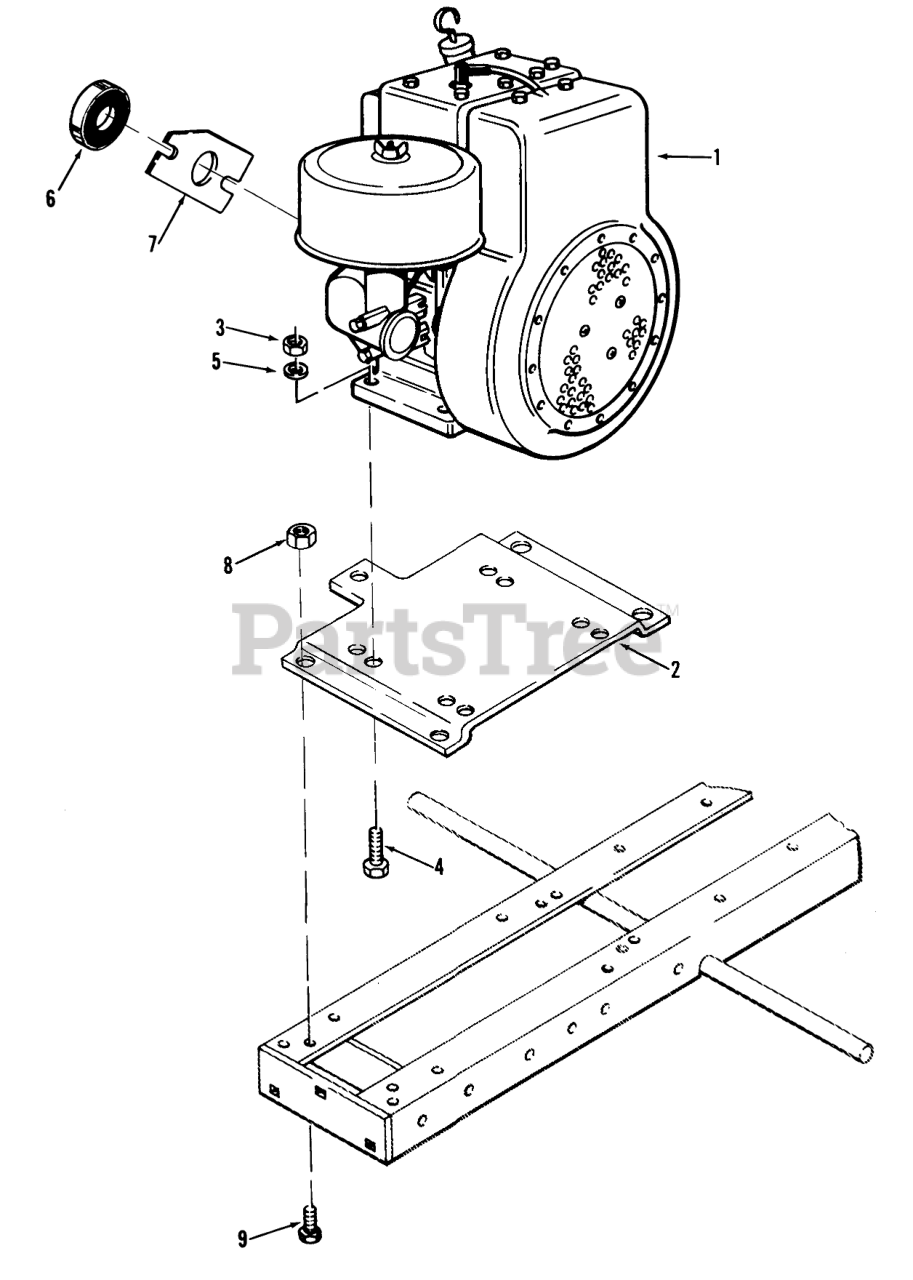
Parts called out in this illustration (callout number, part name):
1	Engine-11 HP Briggs & Stratton 252417 Type 0198-01
2	Engine Cradle
3	Nut
4	HHCS
5	Lockwasher
6	BEARING-BALL
7	PLATE-THRUST B
8	NUT
9	BOLT
